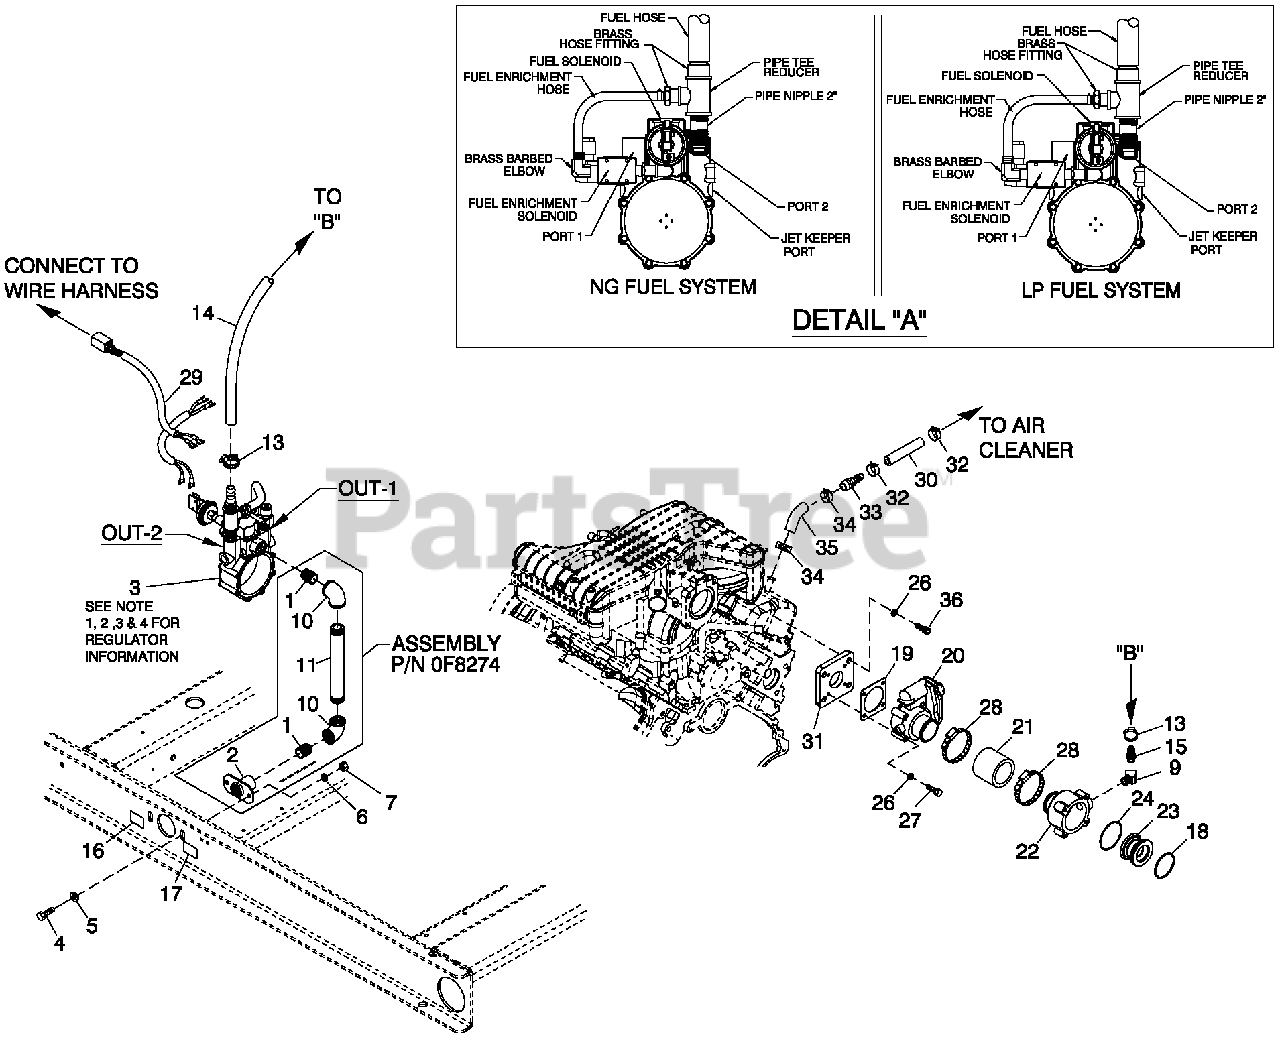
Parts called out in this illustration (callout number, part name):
1	NIPPLE CLOSE 3/4X1.375
2	FLANGE FUEL INLET
3	REGULATOR ASSY 4.2L 48KW
4	SCREW H HCM8-1.25X20 G8.8
5	WAS HER FLAT 5/16-M8 ZINC
6	WAS HER LOCK M8-5/16
7	NUT HEX M8-1.25 G8 CLEAR ZINC
9	STREET EL 45D 1/2 NPT BRASS
10	ELBOW 90D 3/4 NPT
11	NIPPLE PIPE 3/4 NPT X 7
13	CLAMP HOSE #10 .56-1.06
14	HOSE 3/4 ID SAE-30R2 (22" LG)
15	BARBED STR 1/2 NPTX 3/4
16	DECAL INLET PRESSURE
17	DECAL FUEL INLET NG (NATURAL GAS APPLICATION)
18	O-RING 45.63 ID X 2.62 WIDT
19	GASKET BOSC 32
20	ACTUATOR BOSCH 40 GOVERNOR
21	HOSE COOL 2 IN ID 20R4
22	MIXER ACTUATOR 40MM MACHINED
23	VENTURI T HROTTLE 26MM
24	O-RING 47.625 ID X 2.38 WIDTH
26	WAS HER LOCK M6-1/4
27	SCREW SHC M6-1.0 X 45 G12.9
28	CLAMP HOSE #28 1.32-2.25
29	HARNESS CPL FUEL JUMPER
30	HOSE 3/8 ID SINGLE BRAID (20" LG)
31	INTAKEiADAPTERi4.2LiG3-BOSC
32	CLAMPi OSEiBANDi.63iii
33	HOSE BARB REDUCER 5/8"-3/8"ID
34	CLAMP HOSE BAND .88"
35	HOSE COOL 5/8"ID 250&WP (2" LG)
36	SCREW S HC M6-1.0 X 18 G12.9
